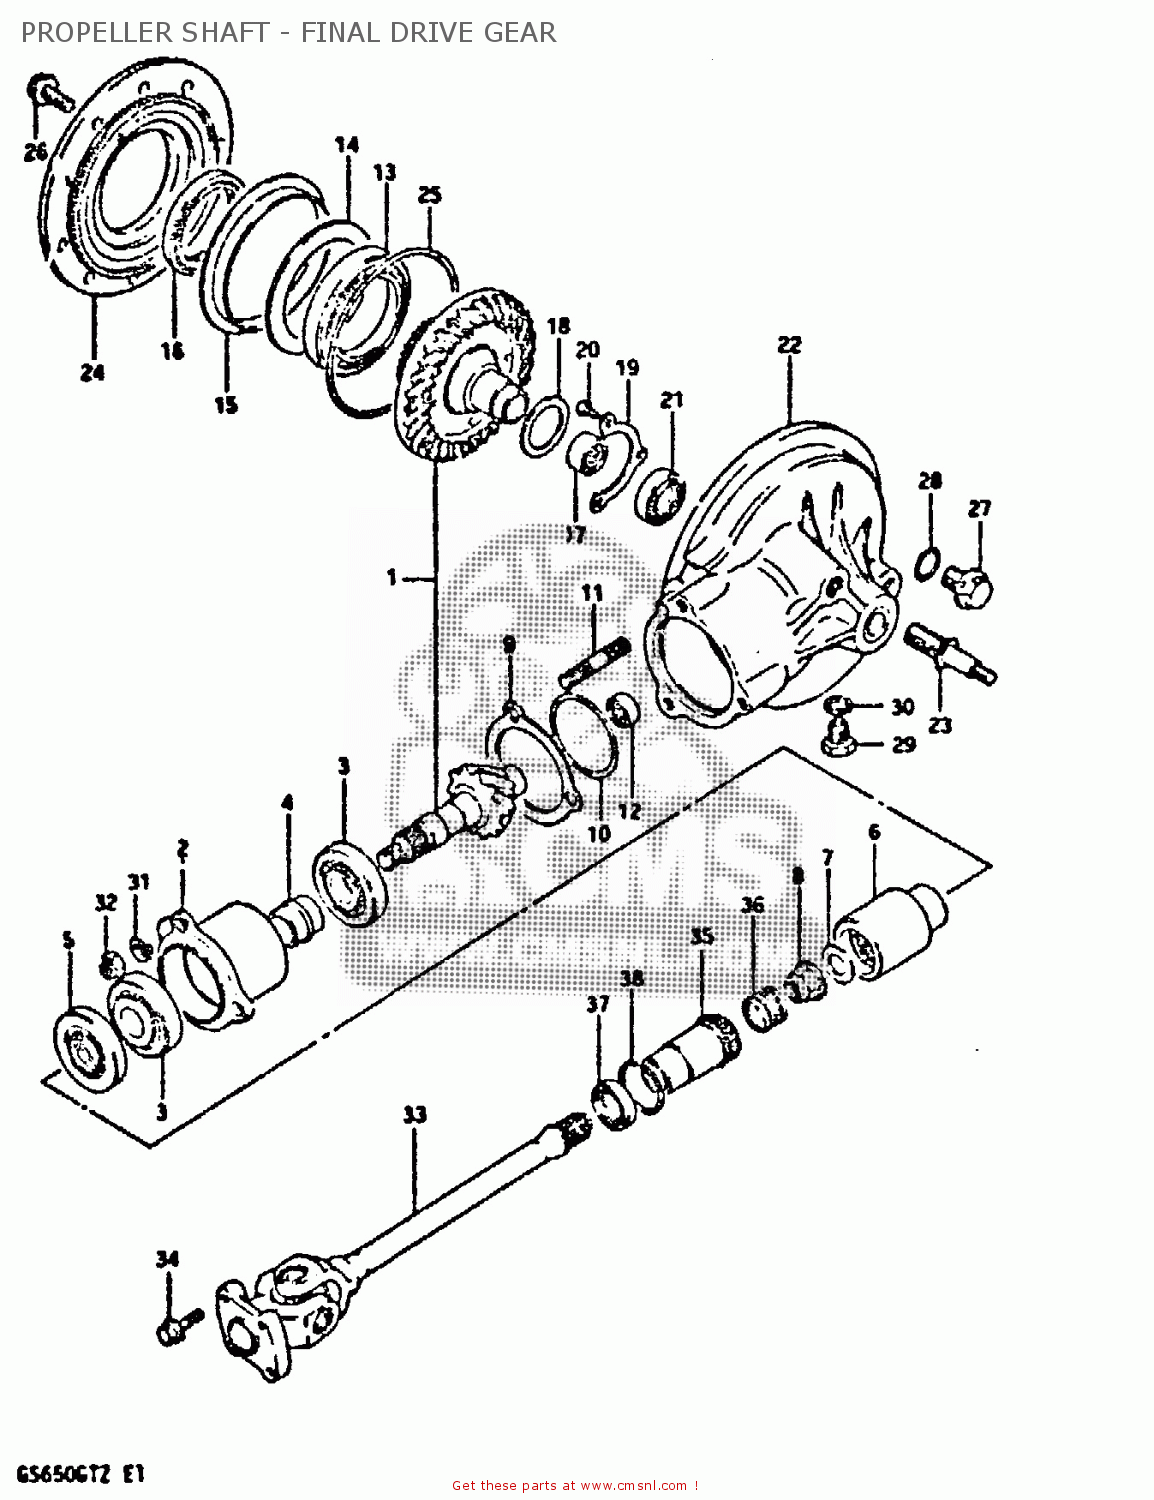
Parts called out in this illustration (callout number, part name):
1	GEAR SET,FINAL BEVEL (N
2	HOUSING,DRIVE GEAR
3	BEARING
4	SPACER
5	SEAL,OIL(32X54X7)
6	GEAR,FINAL DRIVE
7	WASHER(14X29X4)
8	NUT
9	SHIM,DRIVE GEAR HOUSING
10	O RING(D:2.4,ID:62.6)
11	STUD
12	BEARING
13	BEARING(70X110X13)
14	SHIM,DRIVEN GEAR BEARING T0.35
15	PLATE,FINAL DRIVEN BRG OIL
16	SEAL,OIL(70X96X16)
17	BEARING(32X46X17.7)
18	SHIM,FINAL DRIVEN GEAR
19	HOLDER, BEARING
20	SCREW 6X12
21	SEAL,OIL(30X42X7)
22	CASE,FINAL GEAR
23	STUD
24	CASE,FINAL GEAR BEARING
25	O RING(D:3.5,ID:131.6)
26	BOLT
27	PLUG
28	O-RING
29	PLUG
30	GASKET(14X19.2X2) (NAS)
31	LOCK WASHER
32	NUT
33	SHAFT ASSEMBLY,PROPELLER
34	BOLT(8X17)
35	COUPLING,PROPELLER SHAFT
36	SPRING
37	SEAL,OIL(30X40.5X5.5)
38	CIRCLIP
